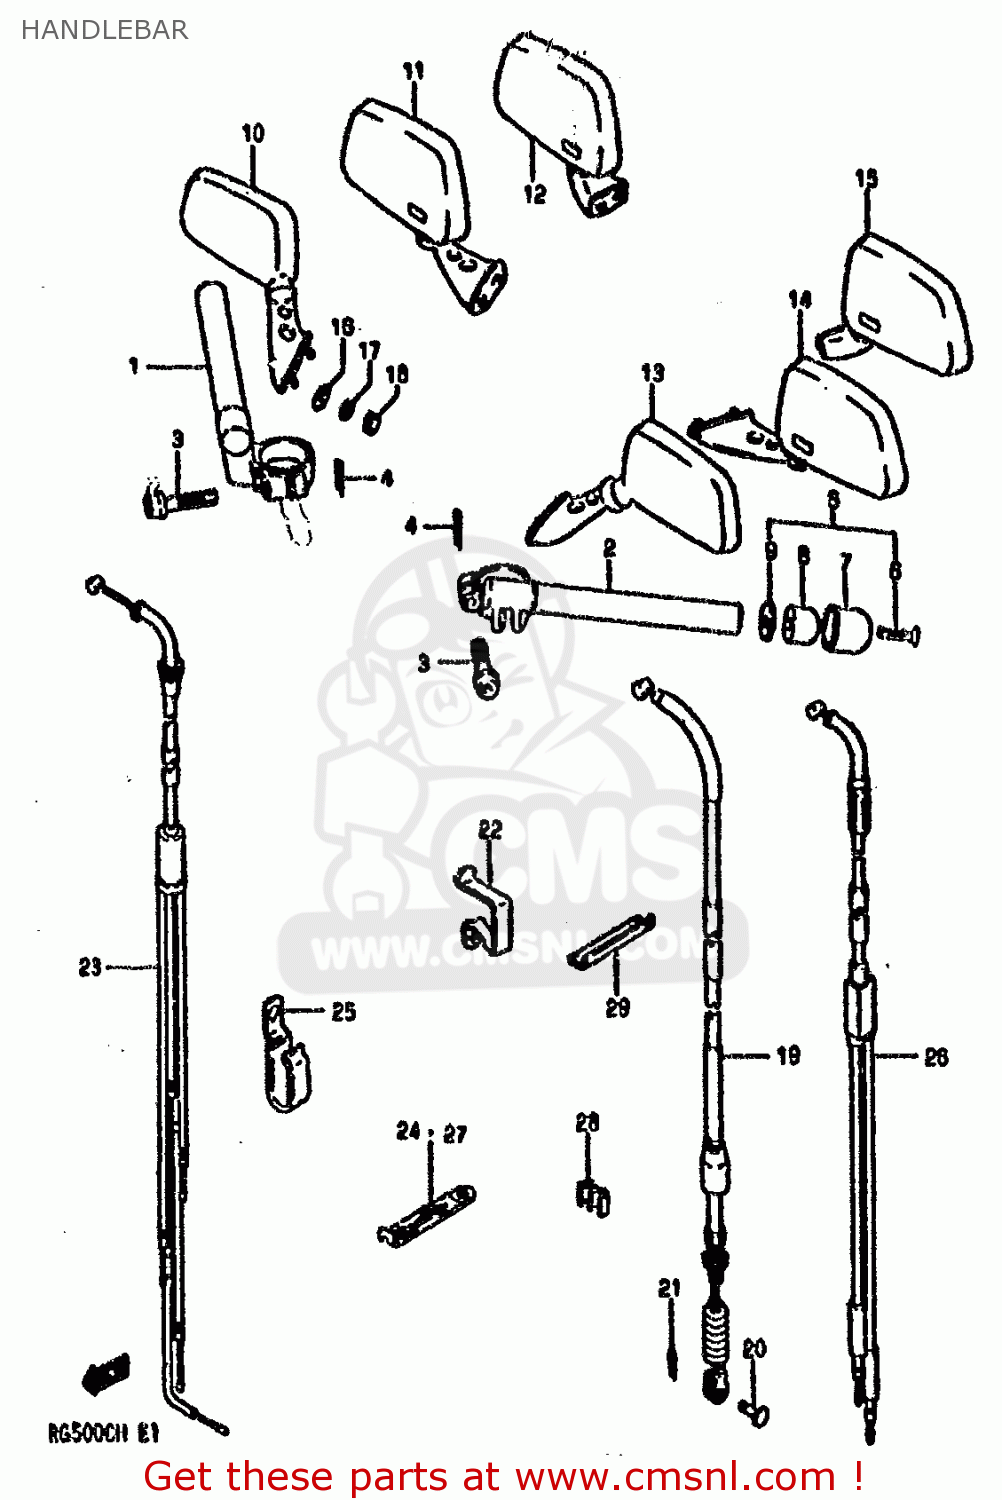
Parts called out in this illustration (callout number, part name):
1	HANDLEBAR,RH
2	HANDLEBAR,LH
3	BOLT
4	COTTER PIN
5	BALANCER SET
6	SCREW
7	CAP,HANDLE BALANCER
8	BALANCER,HANDLEBAR
9	SPACER,BALANCER
10	MIRROR ASSY, REAR VIEW RH
11	MIRROR ASSY,REAR VIEW RH
12	MIRROR ASSY,RH
13	MIRROR ASSY L
14	MIRROR ASSY,REAR VIEW LH
15	MIRROR ASSY,LH
16	WASHER
17	WASHER,LOCK
18	NUT
19	CABLE ASSY,CLUTCH
20	PIN(L:13)
21	PIN
22	GUIDE,CLUTCH CABLE
23	CABLE ASSY,THROTTLE
24	CLAMP
25	GUIDE,THROTTLE CABLE
26	CABLE,STARTER
27	CLAMP
28	CLIP
29	CUSHION,CONTROL CABLE
